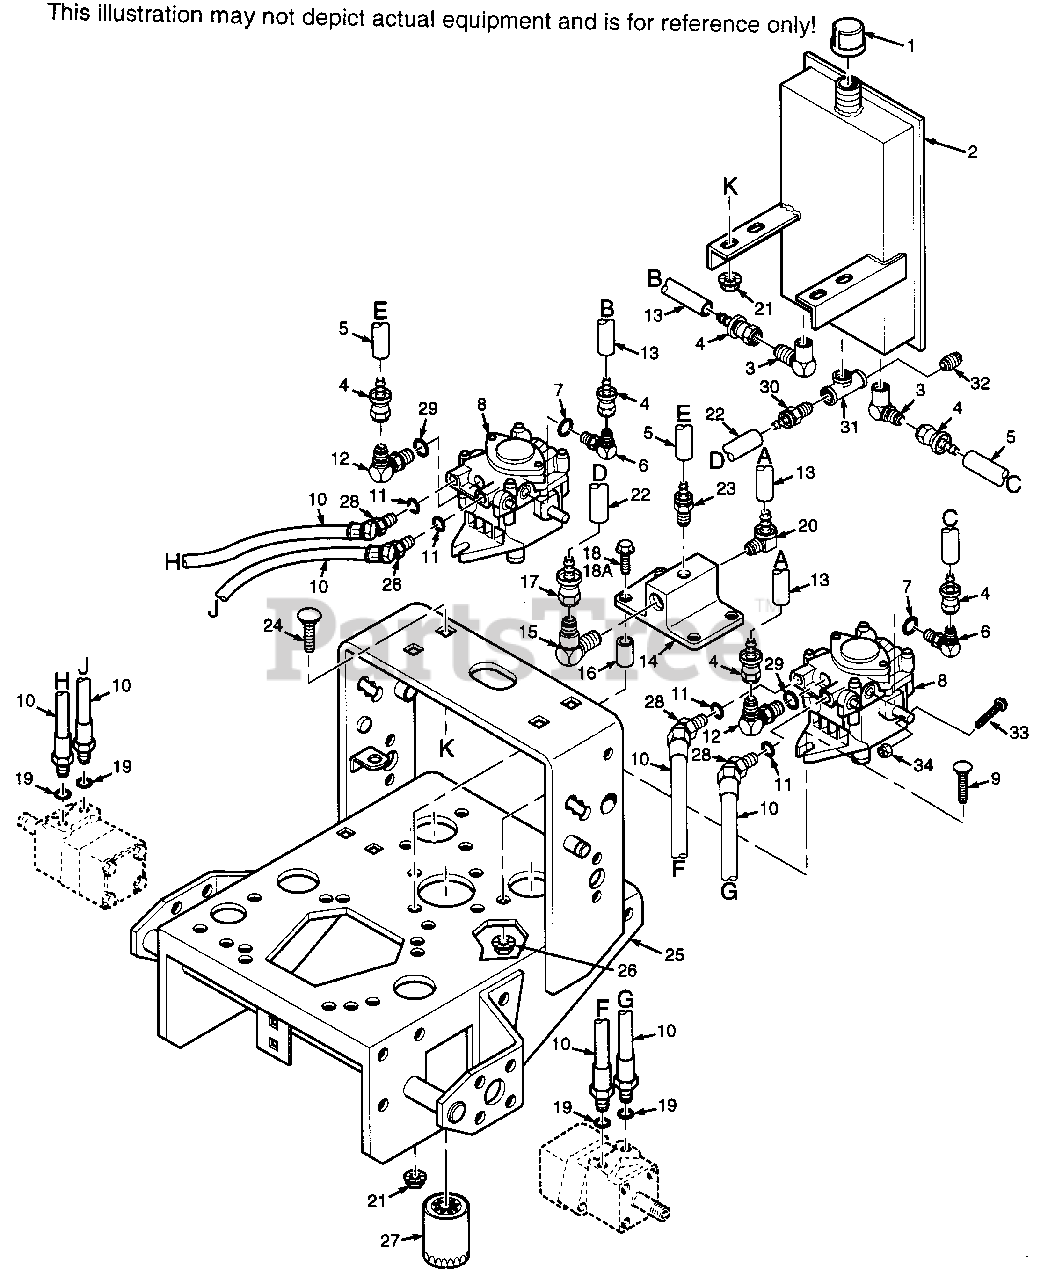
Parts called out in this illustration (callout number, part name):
1	CAP, OIL RESERVOIR
2	OIL RESERVOIR
3	ELBOW, 90 DEG. FEMALE 1/4 NPT TO 1/4 JIC MALE
4	COUPLING, 7/16-20 SAE FLARE SWIVEL TO 1/4"
5	HOSE, 1/4" ID - 12" LONG(ORDER BY THE INCH)
6	ELBOW, 90 DEG. 7/16-20 JIC TO 9/16-18 "O"
7	O-RING
8	PUMP, SUNSTRAND BDP-10L117
9	BOLT, CARRIAGE, 3/8-16 X 1-1/4
10	HOSE, PUMP TO MOTOR
11	O-RING
12	ELBOW, 90 DEG., 7/16-20 JIC X 7/16-20 O-RING
13	HOSE, 1/4" ID - 10" LONG(ORDER BY THE INCH)
14	OIL FILTER BASE
15	ELBOW, 90 DEG. MALE 3/4-16 JIC TO 1/2" MALE
16	SPACER, OIL FILTER BASE(20" FRAME)
17	COUPLING, 3/4-16 SAE FLARE SWIVEL TO 1/2"
18A	CAPSCREW, 5/16-18 X 2.25"(FOR 20") SERR.
19	O-RING
20	ELBOW, 90 DEG. MALE 1/4 NPT TO 1/4 HOSE PUSH
21	NUT, 5/16-18 SERR. FLANGE
22	HOSE, 1/2" ID, 12" LONG(ORDER BY THE INCH)
23	COUPLING, 1/4 STRAIGHT MALE NPT TO 1/4 HOSE
24	BOLT, 5/16-18 X 3/4" CARRIAGE
25	ENGINE DECK(20" WIDE) W/DECALS
26	NUT, 3/8-16 SERR FLANGE
27	OIL FILTER
28	ELBOW, 45 DEG.-3/4-16 JIC MALE X MALE 3/4-16
29	O-RING
30	COUPLING, 3/8 STRAIGHT MALE NPT TO 1/2
31	T-FITTING, 3/8 NPT
32	PLUG, 3/8-18 NPTF MAGNETIC
33	SCREW, 1/4-20 X 2.0" ROUND HEAD PHILIPS
34	NUT, 1/4-20 ELASTIC STOP
